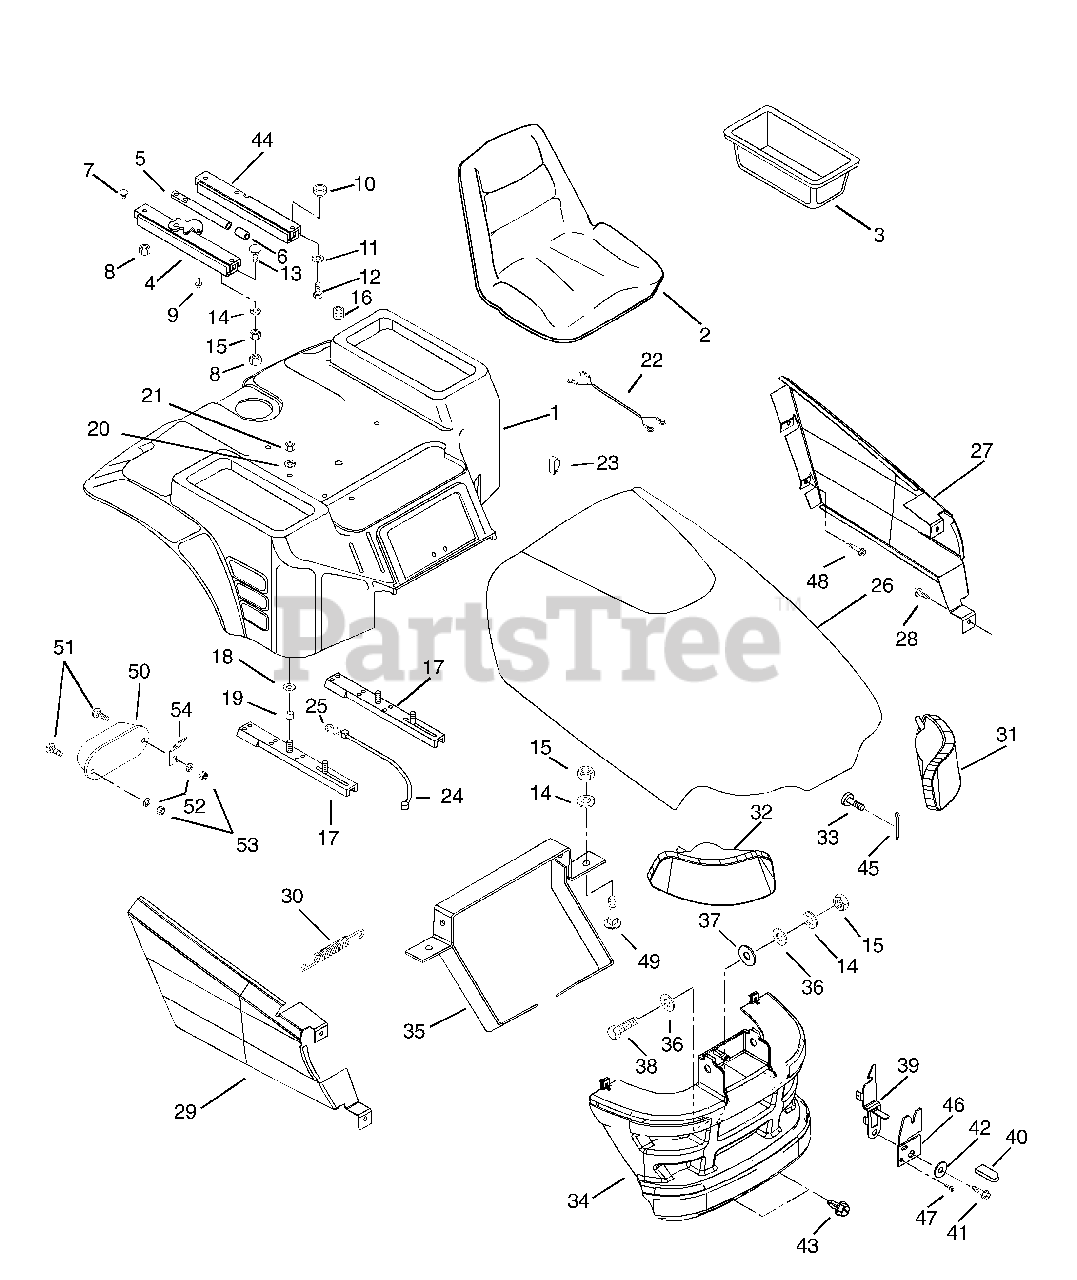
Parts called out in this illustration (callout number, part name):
1	REAR DECK
2	SEAT V-850
4	SEAT SLIDE R H
5	SEAT SLIDE HANDLE
7	SCR-CAP BTHD.31-18X.50 GR5 YZ
8	@NUT-LK-CTR .31-18 YWZC
9	RVT-POP.187X.562 DOME ST
10	SEAT SLIDE SPACER
11	@WSHR-LK-EXT.326X.599X.031YWZC
12	SCR-MCH .31-18X1.00 CRRH YWZC
13	SCR-CAP BTHD.31-18X.875 GR5 PK
14	WSHR-LK .312X.097 HVY YWZC
15	@NUT-HEX .31-18 YWZC
16	GROMMET
17	SEAT SUPPORT
18	WSHR-FL-STL .390X.75X.125 YWZC
19	SPACER .380X.503X.281
20	@WSHR-LK .38X.094 REG YWZC
21	@NUT-HEX .38-16 YWZC
22	SEAT HARNESS
23	WIRE CLIP
26	HOOD WITH DECALS
27	SIDE PANEL- LH
28	SCR-TAP 12-16X.500 HI-LOTPHBL
29	SIDE PANEL- RH
30	SG-TENS .035X.45X2.75 WLD 3.5
31	HEADLIGHT- LH
32	HEADLIGHT- RH
33	PIN, CLEVIS .243/.248X1.50 YWZ
34	GRILLE
35	MOUNT - GRILLE
36	WSHR-FL-STL .328X1.0X.094 YWZC
37	WSHR-FL-NYL .390X1.000X.062
38	@BLT-HEX .31-18X1.00 GR5 YWZC
39	HOOD LATCH
40	GRIP .062 X .375 X 1.000 RE
41	SCR-TAP 12-24X.50 HWH TR BLACK
42	WSHR-FL-STL .281X1.250X.048 BL
43	@SCR-TAP .31-18X.75 HWH TR YWZ
44	SEAT SLIDE L H
45	@PIN-CTR .09X.75 EXTPRSQCT YWZ
46	LOCATOR- HOOD
47	SCR-TAP 10-12X.50 CRPH PL A BL
48	SCR-TAP 10-16X.62 SLPH AB YWZC
49	@BLT-RDHDSQNK .38-16X1.00 G2YZ
50	TAIL LIGHT ASSEMBLY W/BULLET
51	SCR-MCH 10-24X.50 SLRH YWZC
52	@WSHR-LK #10X.047 REG YWZC
53	@NUT-HEX 10-24 YWZC
54	MALE DISCONNECT ADAPTER
